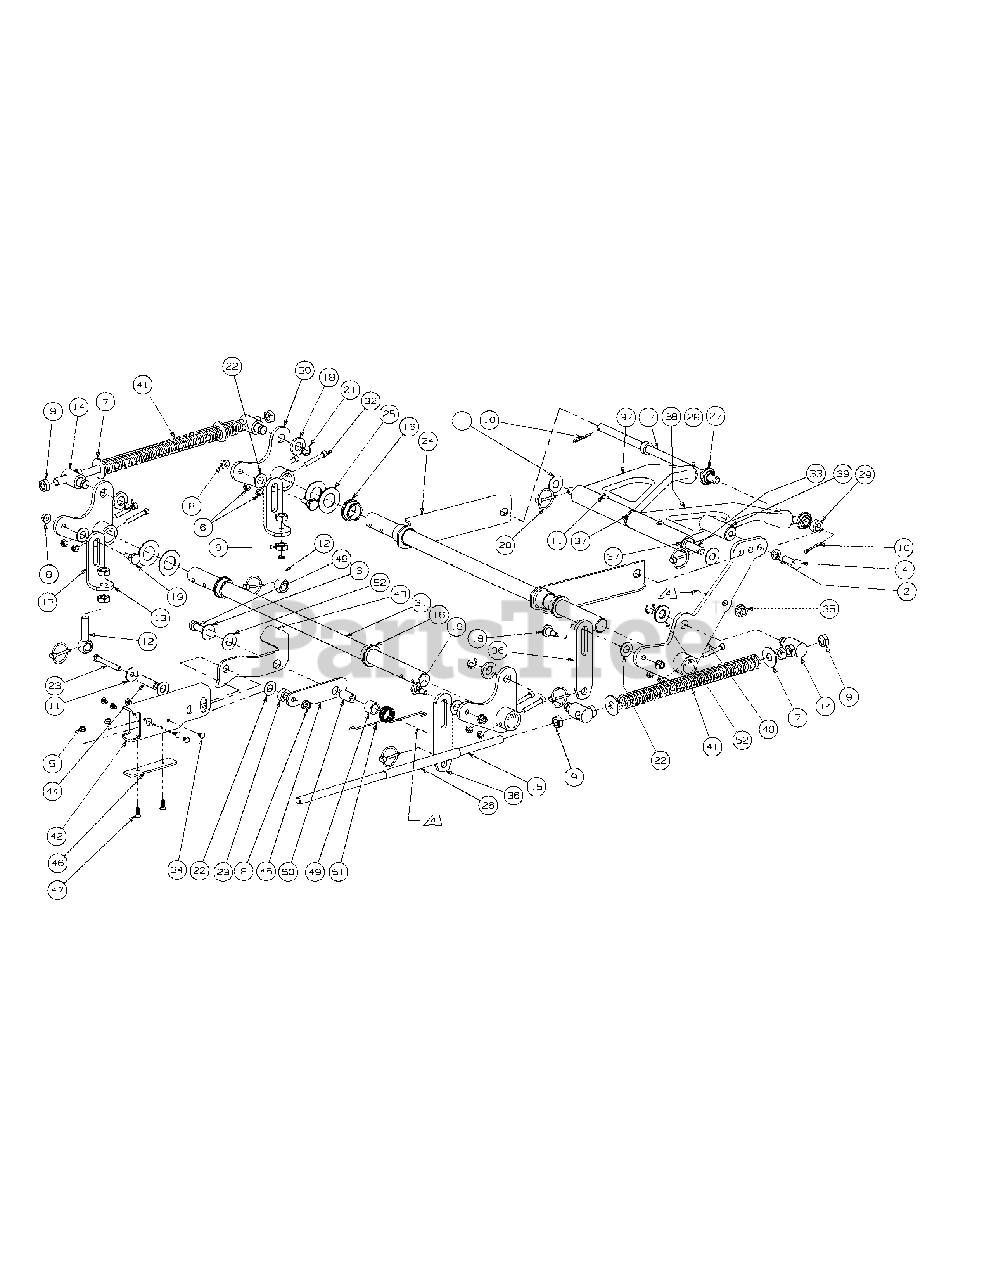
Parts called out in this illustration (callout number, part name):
1	Washer, 1.5 x .655 x .055
2	Lock Washer, 1/2
3	Flat Washer, 1/2
4	Hex Cap Screw, 1/2-13 x 1.50
5	Lock Nut w/Nylon Insert
6	Nut, 5/16-18, Nylock
7	Flat Washer, 5/8
8	Hex Nut, Flange Lock, 3/8-16
9	Jam Nut, 5/8-11
10	Cotter Pin, 3/16 x 1-1
11	Flat Washer, 1.25 x .411 x .100
12	Eye Bolt, 5/8ID
13	Eye Bolt Mount Link, 5/8 ID
14	Ferule Lift
15	Lift Connector Rod
16	Hex Flange Bearing, 1.25 ID
17	Front Lift Link, Rod Mount
18	Spacer, .812 ID x .268 Lg.
19	Shoulder Screw, 0.625 OD x .437 Lg.
20	Linch Pin, 3/16 Dia.
21	E Clip, 3/4 Dia.
22	Nylon Flat Washer, 5/8
23	HHCS, 3/8-16, 3.00
24	Front Frame Strut Assembly
25	Flat Washer, 1.25 ID
26	Hose, 5/8 ID 13/16 OD, 8" LG
27	Rod End, Male
28	Jam Nut, 5/8-18
29	Spacer, .630 ID x 1.06 OD x .440
30	Bellecrank Weldment Assembly
31	Deck Lift Shaft
32	Socket Head CapScrew, 5/16-18 x 2
33	Lift Link Rod
34	Rivet, 1/4 x 5/8
35	Nut, 1/2-13, FlangeLock
37	Bearing Lift Brace Assembly, Left Hand includes:
38	Bearing Lift Brace Assembly, Right Hand includes:
39	Deck Lift Foot Pedal
40	Deck Lift Foot Pedal Weldment
41	Lift Compression Spring
42	Lift Tube, 3.0 x 1.5
43	Lift Link Bracket
44	Spacer, .375 ID x .625 OD x 1.53
45	Yoke Plate
46	Lift Wear Plate
47	Flat Head Cap Screw, 1/4-20 x .75
48	HHCS, 1/2-13 x 2.50
49	Spacer, .76 ID x 1.0 OD x .75
50	Spacer, .50 ID x .75 OD x 1.313
51	Torsion Spring, .120 Wire x 1.32 OD
52	Washer, .76 x 1.49 x .06
